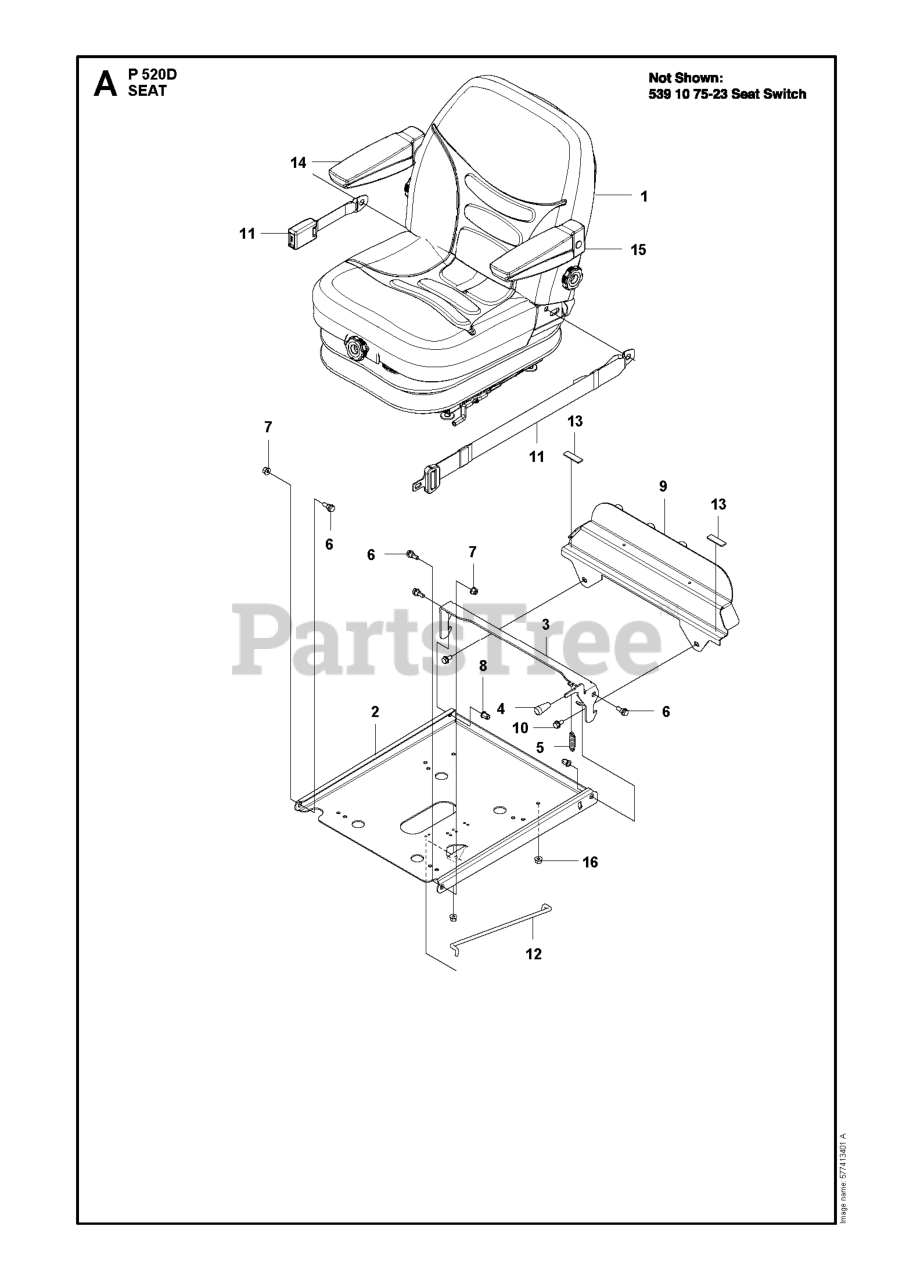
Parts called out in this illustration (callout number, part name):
5	DRAW SPRING L=50
7	NUT FLANGE
16	5/16-18 NYLOC FLANGE NUT
